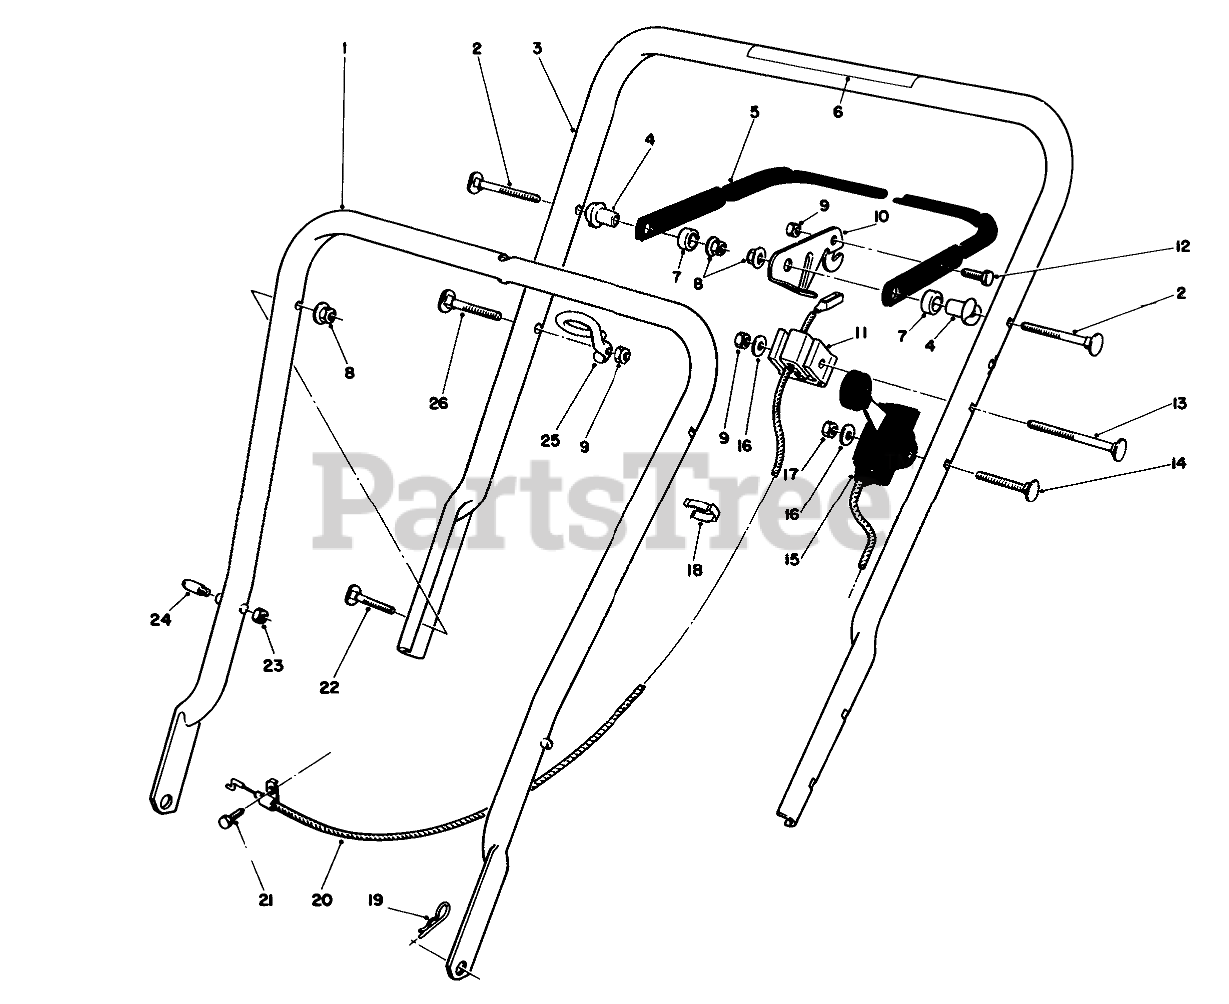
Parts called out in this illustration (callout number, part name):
1	LOWER HANDLE ASM
2	5/16-18 X 2 HNDLE SCREW
3	Handle-Upper (Incl. Ref. #6)
4	SPACER-SUPPORT
5	Bar-Control
6	Decal-Danger
7	SPACER-NYLON
8	NUT-LOCK, NI
9	NUT-LOCK, NI
10	Lever-Control
11	SUPPORT-CABLE
12	SCREW-HH
13	HANDLE SCREW
14	SCREW-HANDLE
15	SERVICE THROTTLE CONTRO
16	WASHER-FLAT
17	NUT-LOCK, NI
18	BOWDEN CLIP
19	PIN-COTTER, HAIR
20	BRAKE CABLE
21	SCREW-HH
22	SCREW
23	NUT-LOCK, NI
24	HANDLE PIN
25	Guide
26	HANDLE SCREW
